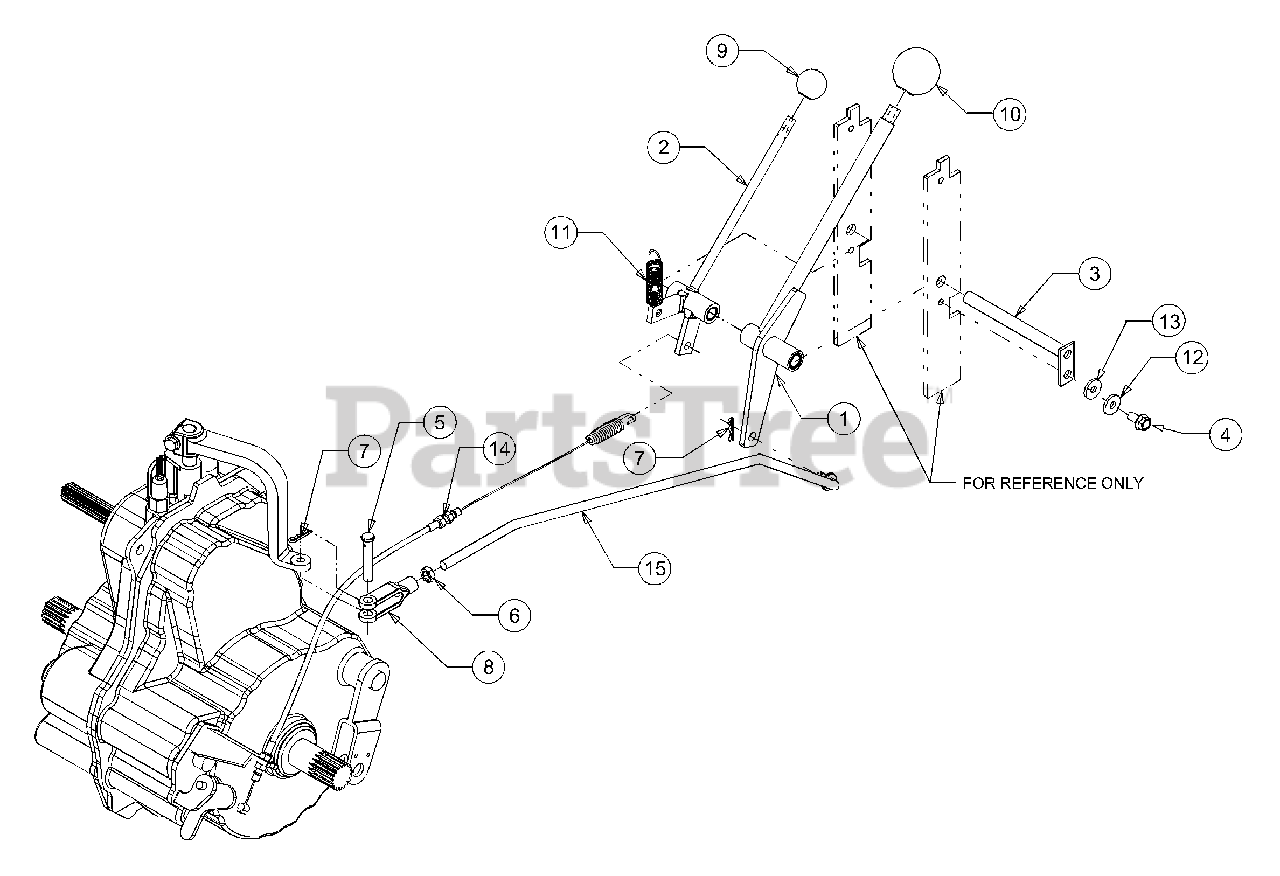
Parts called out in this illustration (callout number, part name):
1	Lever Assembly, Transmission
2	Shifter Assembly, Differential Lock
3	Pin Assembly, Transmission
4	Hex Screw, Flange, 5/16-18 x .75, Gr5
5	Pin, Clevis, .375 x 2.0
6	Nut, Jam, 3/8-24
7	Pin, Cotter, .072 x 1.13
8	Clevis, Adjustment
9	Knob, Ball
10	Knob, Ball
11	Spring, Extension, .637 x 2.972
12	Lock Washer, 5/16
13	Flat Washer, .330 x .687 x .030
14	Control Cable, Differential Lock
15	Shifter Rod, Transmission
